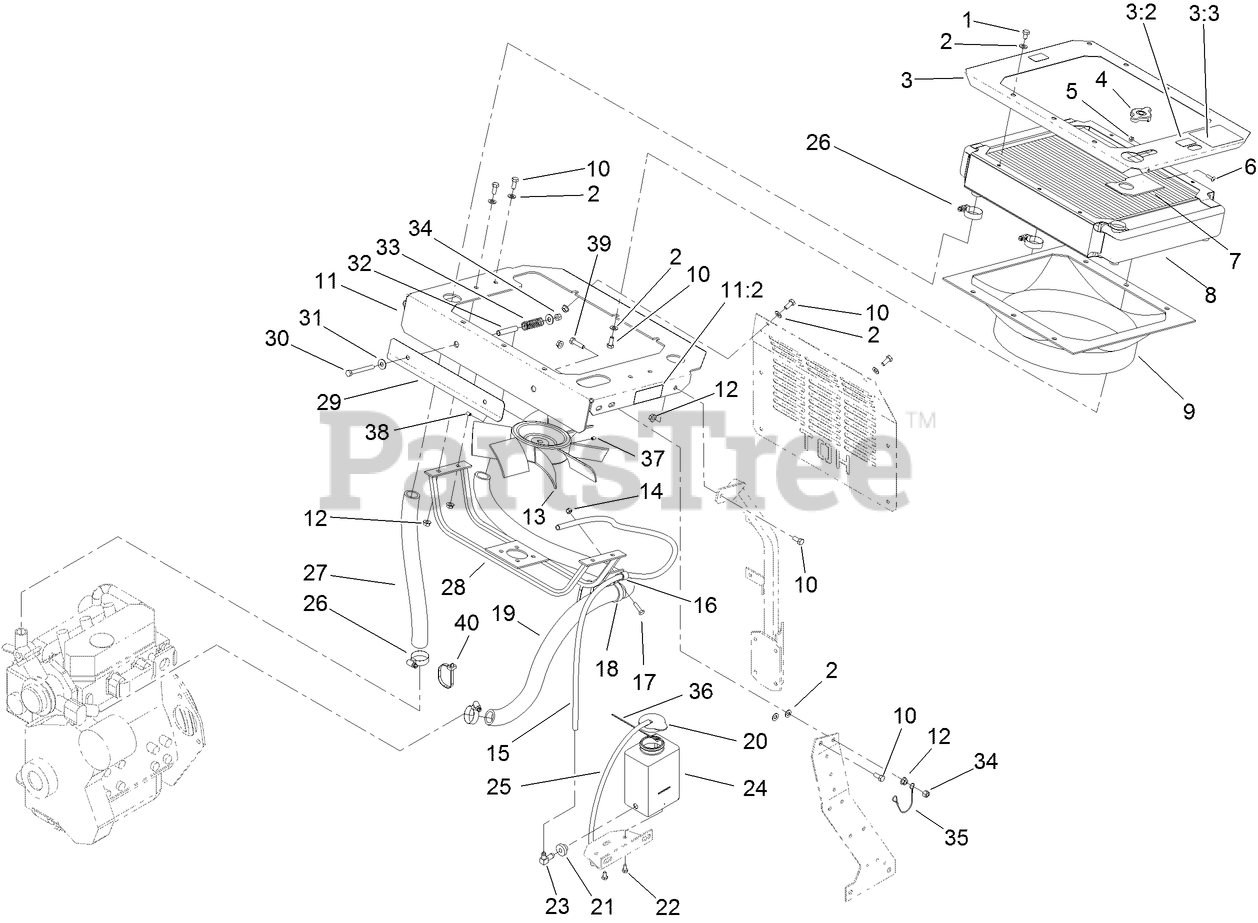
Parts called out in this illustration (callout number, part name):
1	SCREW-HH
2	WASHER-PLAIN
3	PLATE-TRIM, RADIATOR
3:2	DECAL-SURFACE, HOT
3:3	DECAL-COOLANT
4	CAP-RADIATOR
5	NUT-LOCK, NI
6	SCREW-HEAD, TRUSS
7	SHIELD-FILL NECK, RADIATOR
8	RADIATOR
9	SHROUD-COOLING, ENGINE
10	SCREW-HH
11	FAN MOUNTING PLATE ASM
11:2	DECAL-FAN, RADIATOR
12	NUT-HF
14	NUT-LOCK, NI
16	CLIP-LOOM
17	SCREW-HH
18	CLIP-LOOM
19	HOSE-INLET, ENGINE
20	CAP-TANK, OVERFLOW
22	SCREW-HH
24	TANK-OVERFLOW
27	HOSE-OUTLET, ENGINE
28	MOUNT-MOTOR, FAN
29	BRACKET-DEFLECTOR, AIR
30	SCREW-HH
31	WASHER-FLAT
32	SPACER
33	SPRING-INDICATOR, REVERSE
34	NUT-LOCK, NI
35	LANYARD
36	TIE-CABLE
37	SCREW-SET
39	SCREW-HH
40	TIE-PLASTIC
